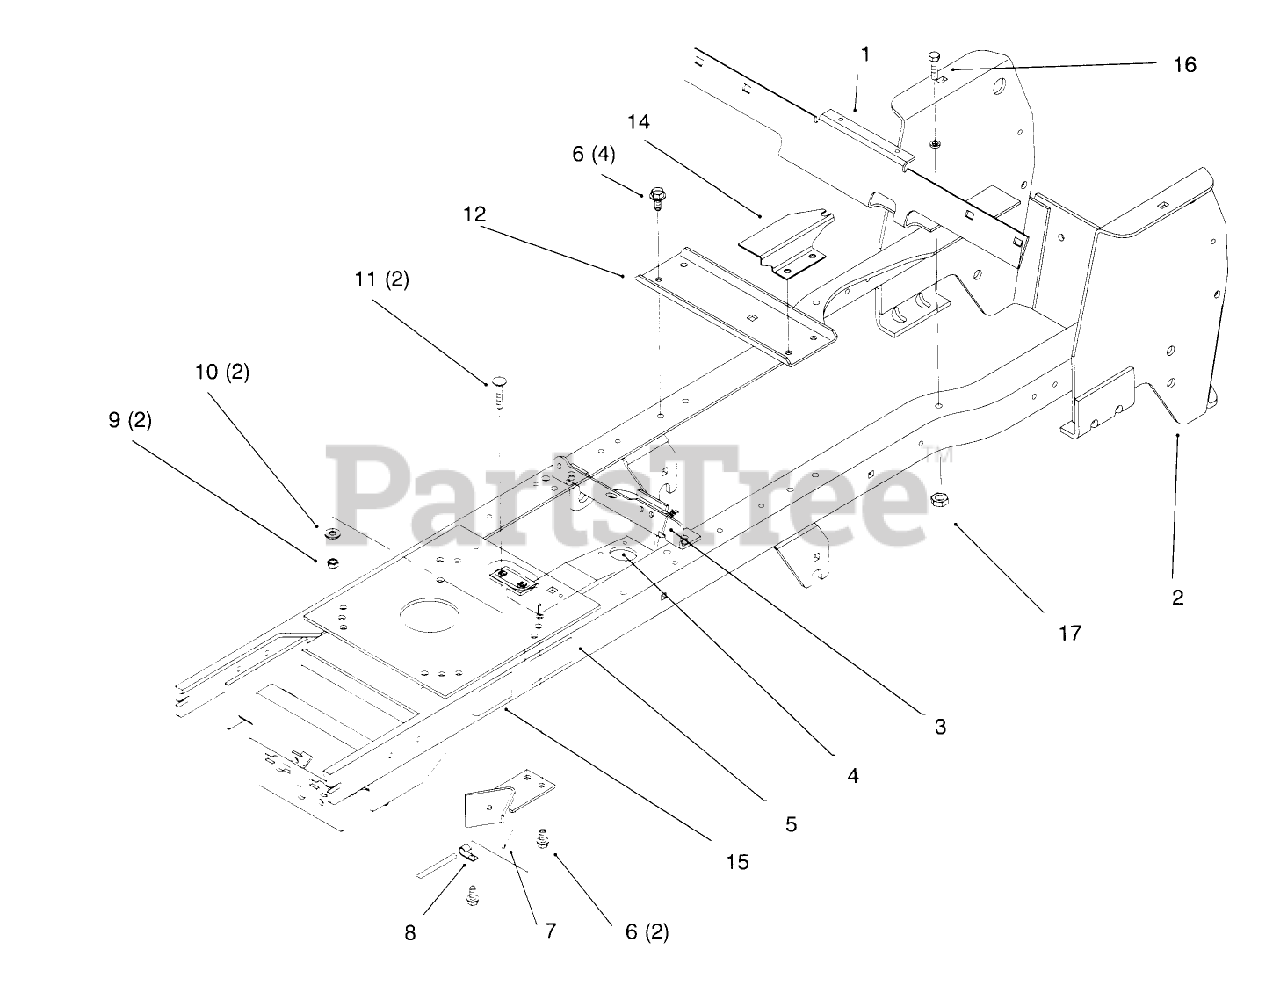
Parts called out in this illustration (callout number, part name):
3	TIE-CABLE
6	SCREW-HWHTF
7	PTO STOP ASM
8	CLIP
9	NUT-LOCK, NI
10	WASHER-PLAIN
11	BOLT-CARR
12	BRACKET-IDLER PLATE
14	BRACKET-HOC GAGE
15	SCREW-HH
15	DECAL-ATTACH A-MATIC
16	SCREW-HH
17	NUT-LOCK, NI
